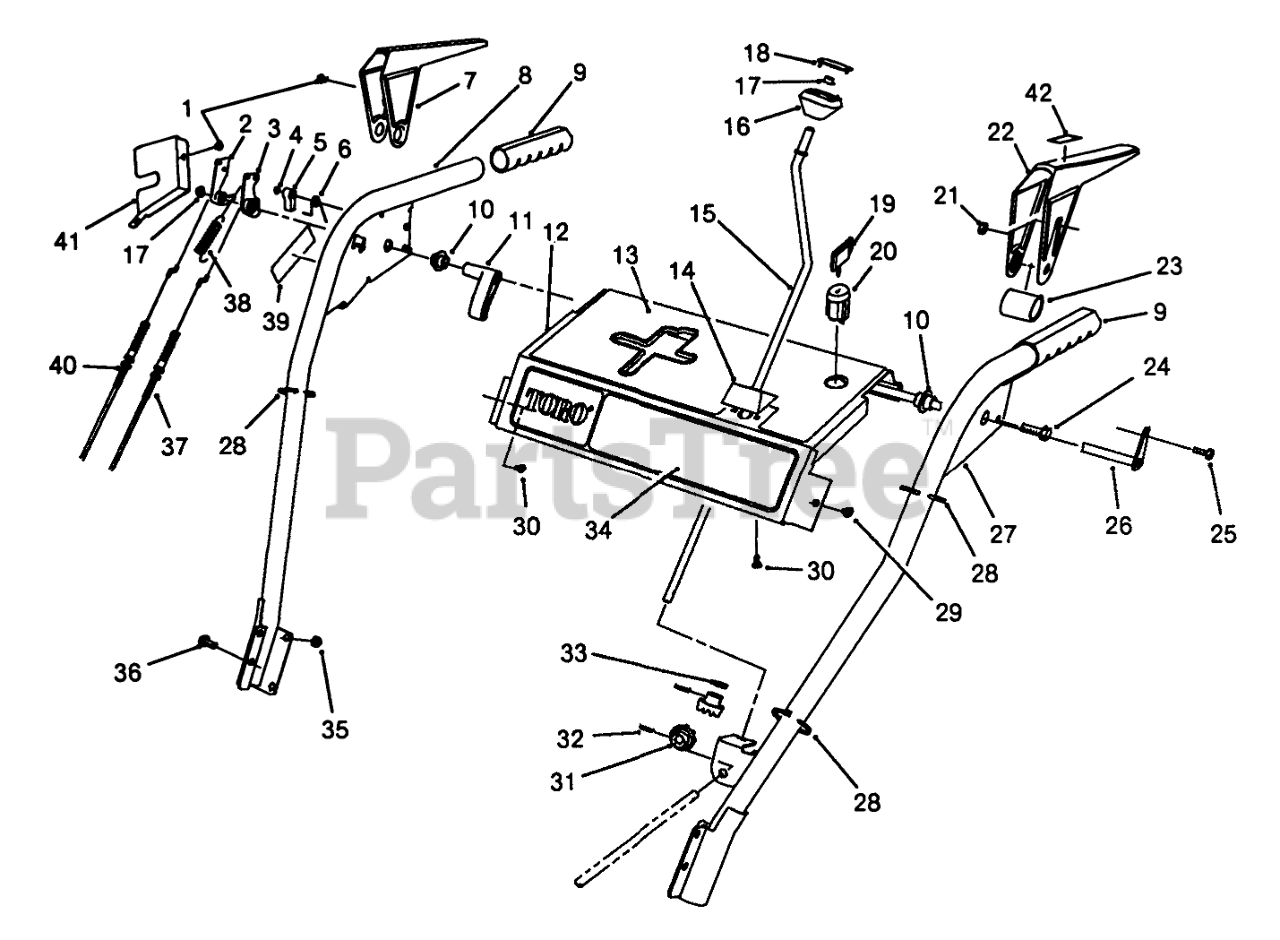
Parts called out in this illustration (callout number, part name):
1	SCREW-HH
2	TANG-LOCKING
3	CAM-RELEASE
4	E-RING-RETAINER
5	LATCH-LOCKING
6	SPRING-TORSION
7	Lever-Impeller
8	Handle-RH
9	HANDLE GRIP
10	BUSHING-LEVER
11	LEVER-TRIP
12	Panel-Control
13	Decal-Panel, Top
14	PLATE-GUIDE
15	CRANK-ROD, CHUTE
16	KNOB-CONTROL, CHUTE
17	RETAINER-PUSH ON
18	COVER-KNOB
19	KEY-IGNITION
20	SWITCH
21	NUT-LOCK, NI
22	Lever-Traction
23	SPACER-LEVER, TRACTION
24	SCREW-HHF
25	SCREW-HWH
26	CROSS ROD ASM
27	LH HANDLE WA (24")B
28	TIE-CABLE
29	SCREW-HWHTF
30	SCREW-PPH
31	GEAR-UNIVERSAL
32	PIN-SPRING
33	WASHER-RUBBER
34	DECAL-FRONT PANEL
35	Locknut
36	SCREW-HHF
37	CABLE-TRACTION
38	Spring-Extension
39	Decal-Warning
40	CABLE-IMPELLER
41	Cover Lever Lock
42	DECAL-LEVER
